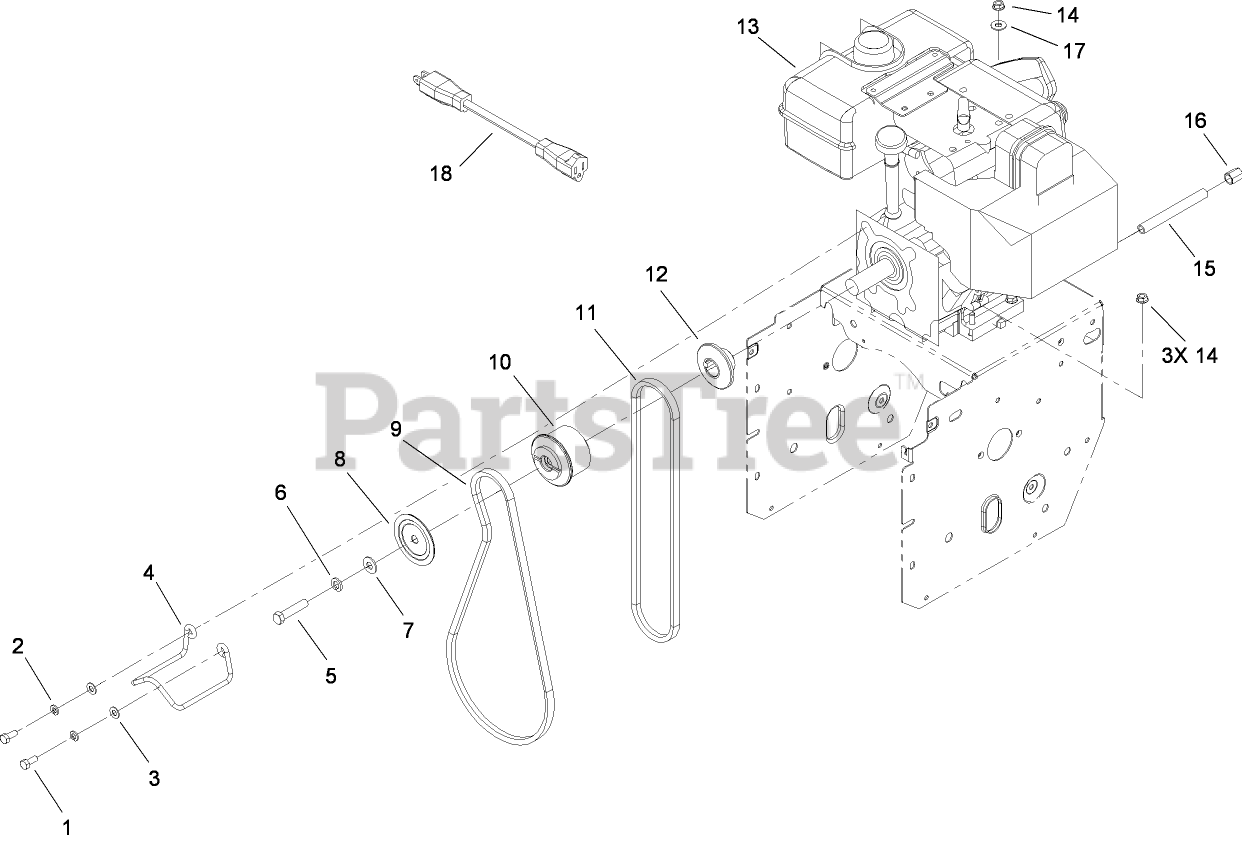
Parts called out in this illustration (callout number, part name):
1	SCREW-HH
2	WASHER-LOCK
3	WASHER-PLAIN
5	SCREW-HH
6	WASHER-LOCK
7	WASHER-FLAT
8	SHEAVE-HALF, IMPELLER
9	BELT-V
10	PULLEY-ENGINE, CENTER
11	V BELT-TRACTION
12	SHEAVE-HALF, TRACTION
13	Loose Parts Package
14	NUT-HF
15	NIPPLE-PIPE
16	CAP-PIPE
17	WASHER-FLAT
18	CORD-EXTENSION (only on: 38078)
